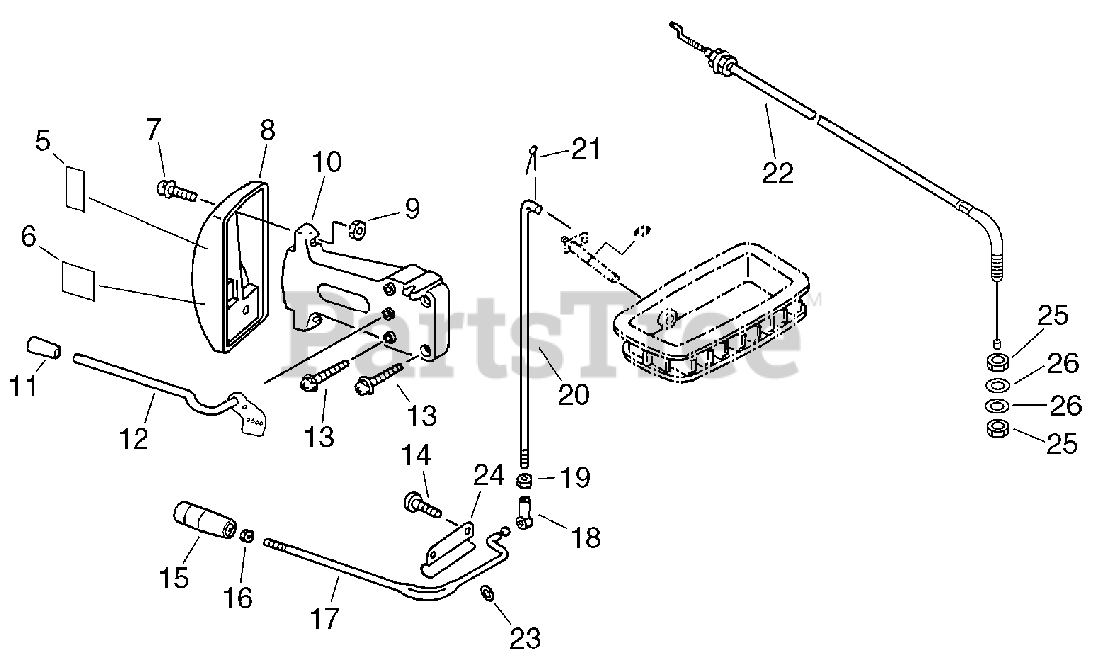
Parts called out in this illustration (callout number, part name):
5	LABEL - SPEED
6	LABEL - STOP
7	SCREW - 5X25
8	DIAL, RATE CONTROL
10	BRACKET, DIAL
11	KNOB
12	LEVER, THROTTLE CONTROL
13	SCREW - 5X25
14	SCREW - 5X14
17	LEVER, CONTROL
18	CONNECTOR
20	ROD, CONTROL LEVER
21	PIN, SPLIT - 1.8×18
22	CABLE, THROTTLE
23	WASHER - 8
24	BRACKET, LEVER
26	WASHER - 6
